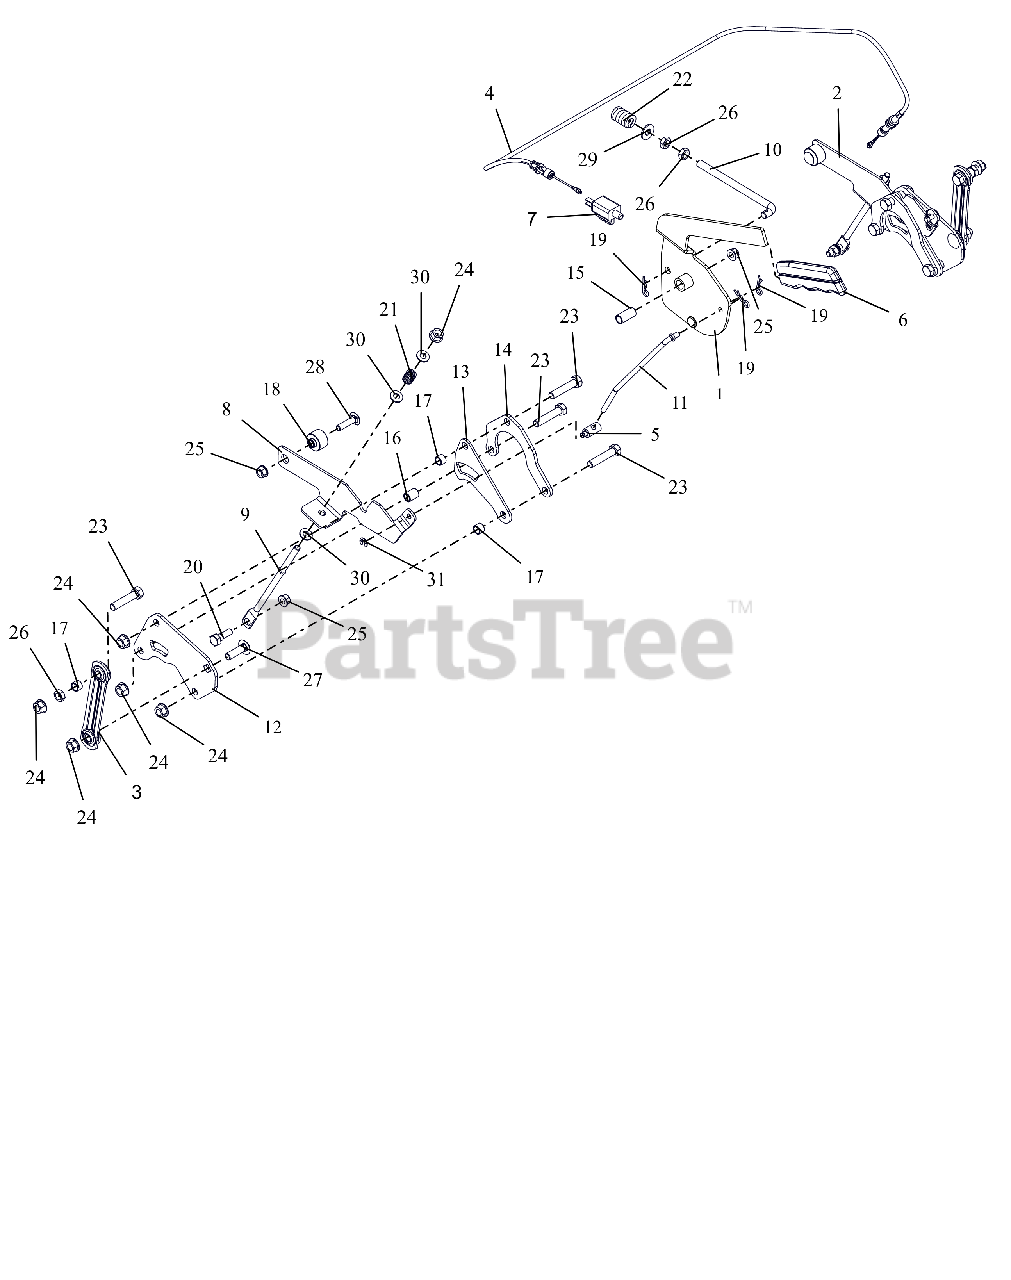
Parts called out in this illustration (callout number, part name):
1	LEVER, PARKING BRAKE
2	ARM, BRAKE - LH (W/PIN)
3	LINK, STAMPED STEERING
4	CABLE, BRAKE
5	TRUNION, 1/4-20
6	GRIP, PARKING BRAKE (YELLOW)
7	SWITCH, SINGLE POLE N.O.
8	ARM, BRAKE-RH
9	ROD, LINK - TRANSMISSION BRAKE
10	ROD, OVER CENTER
11	ROD, BRAKE LINK
12	BRKT, TRANSAXLE STEERING
13	BRKT-SPACER
14	PLATE, REAR REINFORCING
15	BSHG-SLV .385X.500X1.045
16	SPCR, SLV .385X.500X.652
17	SPCR, SLV .385X.500X.350
18	SPCR, FLANGE
19	PIN, HAIR #213 .08X1.19 ZCC
20	BOLT,SHLDR .38X.25 -.31-18X.75
21	SPRING, COMPRESSION
22	SG-COMP .187X.56X1.62
23	BLT, HEX .38-16X1.75 G5 ZCC
24	NUT-LK-TOP-FLG .38-16 ZC120
25	NUT-LK-TOP-FLG .312-18 GF ZCC
26	NUT-JAM .375-16 G2 ZCC
27	BLT,RHSSN .38-16X1.25 G5 ZCC
28	BLT, RHSSN.31-18X1.25 G5 ZCC
29	WSHR,FLT .375X.875X.083 ZCC
30	WSHR,FLT .344X.688X.065 ZCC
31	RG-RTNG-EXT .250X.025
